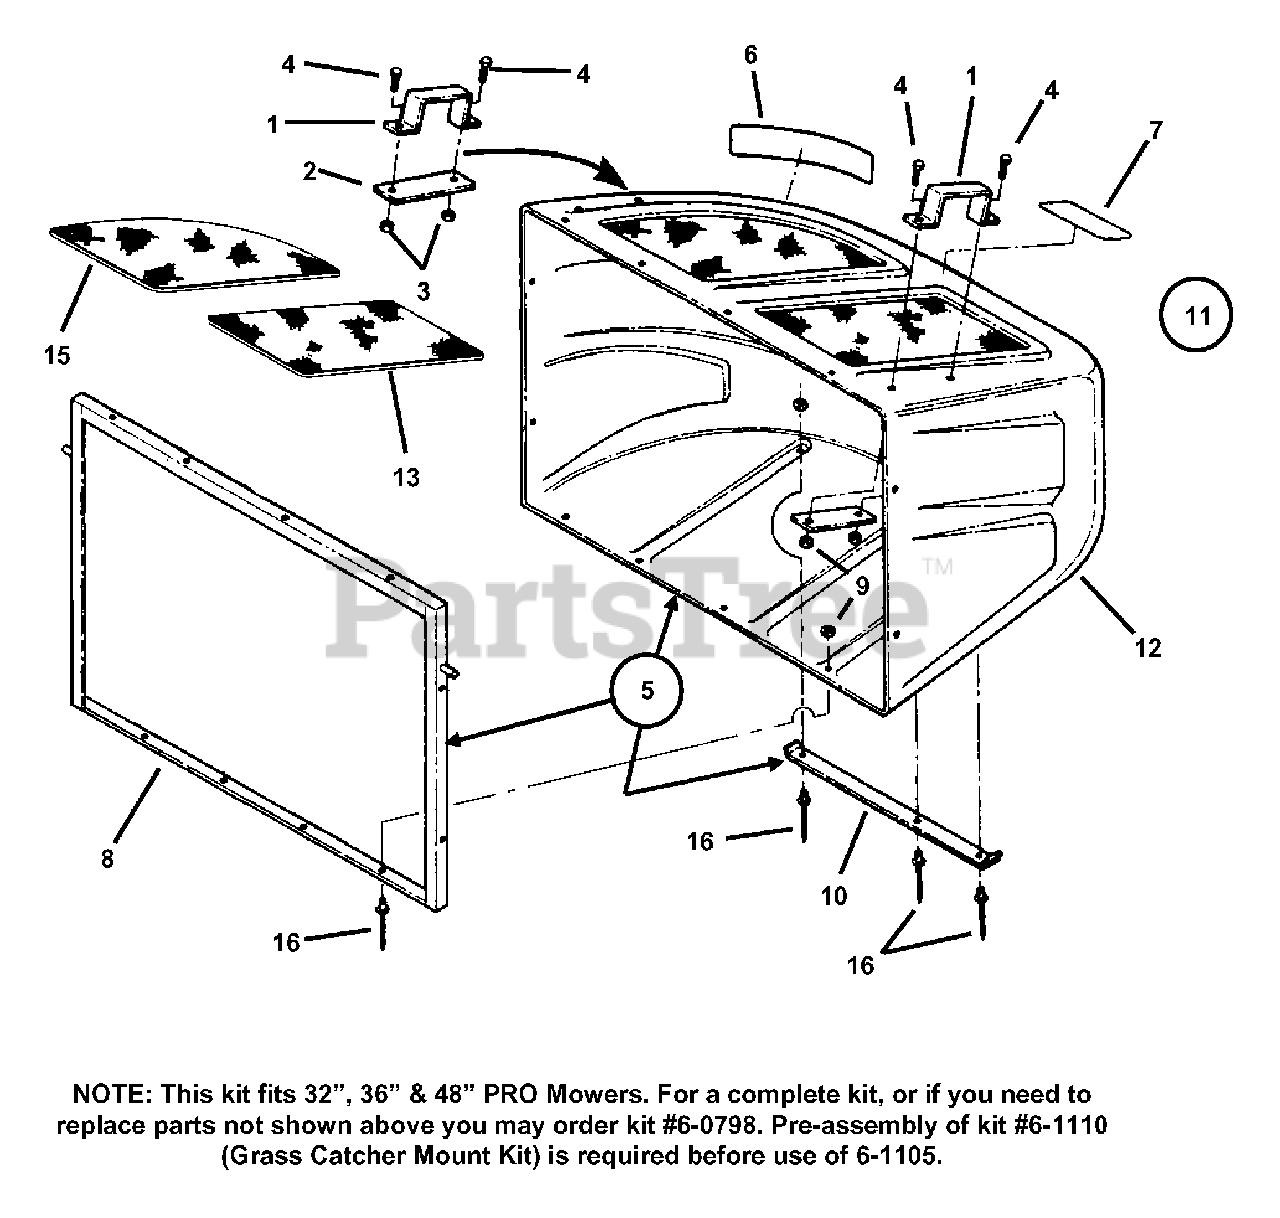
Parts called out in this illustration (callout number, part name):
1	HANDLE, Hopper
2	PLATE, Handle Brace
3	NUT, 1/4-20 Hex Nyloc
4	SCREW, 1/4-20 x 1" Hex Head Cap, Grade 5
5	ASSEMBLY, Hopper with Frame
6	DECAL, Snapper
7	DECAL, Warning
8	FRAME, Hopper
9	WASHER, Grass Catcher
10	PLATE, Skid
11	ASS'Y, HOPPER w/Screens
12	HOPPER, Grass Catcher
13	SCREEN, Top Rear
15	SCREEN, Top Front
16	POP RIVET, 3/16 #66
